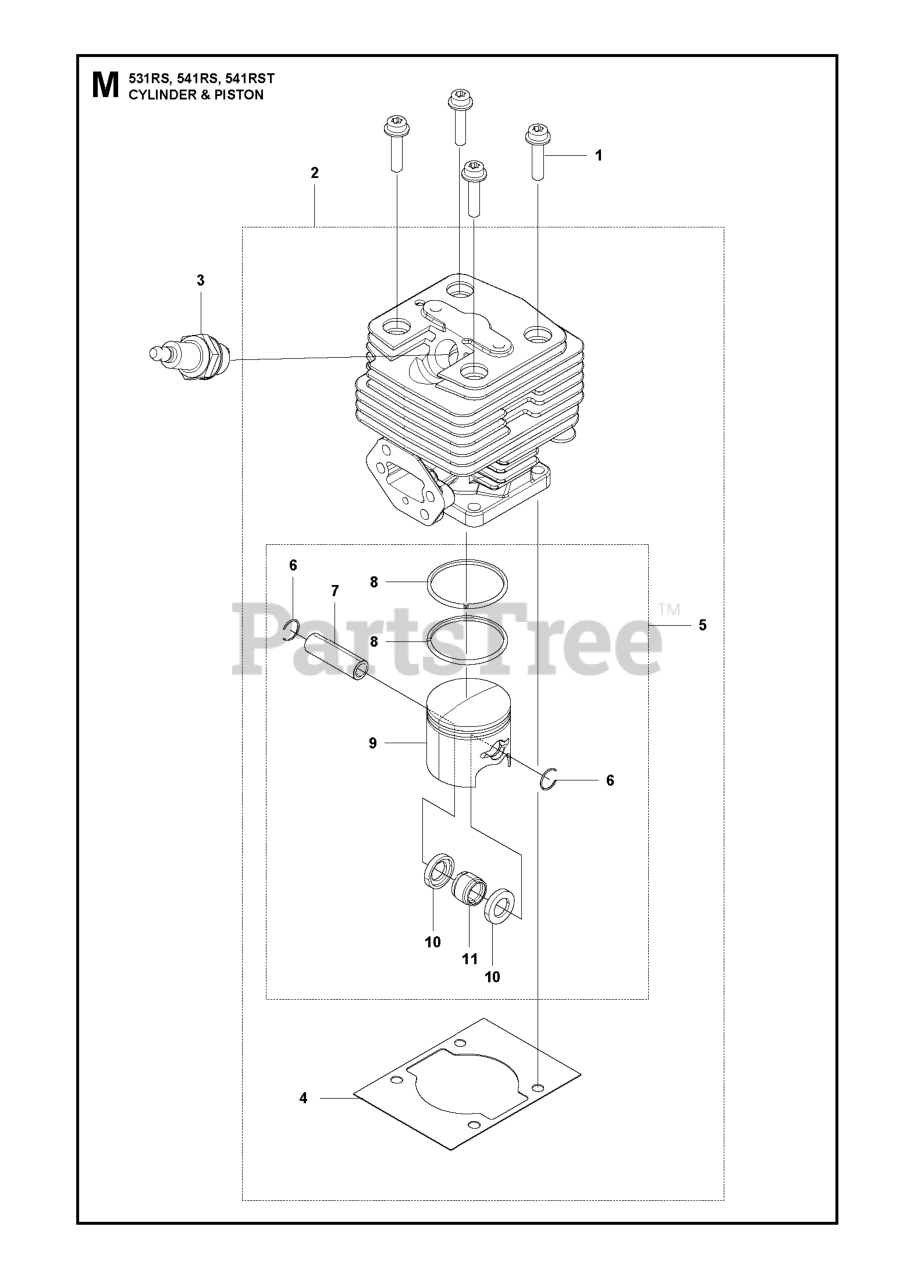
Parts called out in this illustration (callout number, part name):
7	PISTON PIN
8	RING, PISTON 2/PK
9	PISTON
11	ROLLER BEARING
